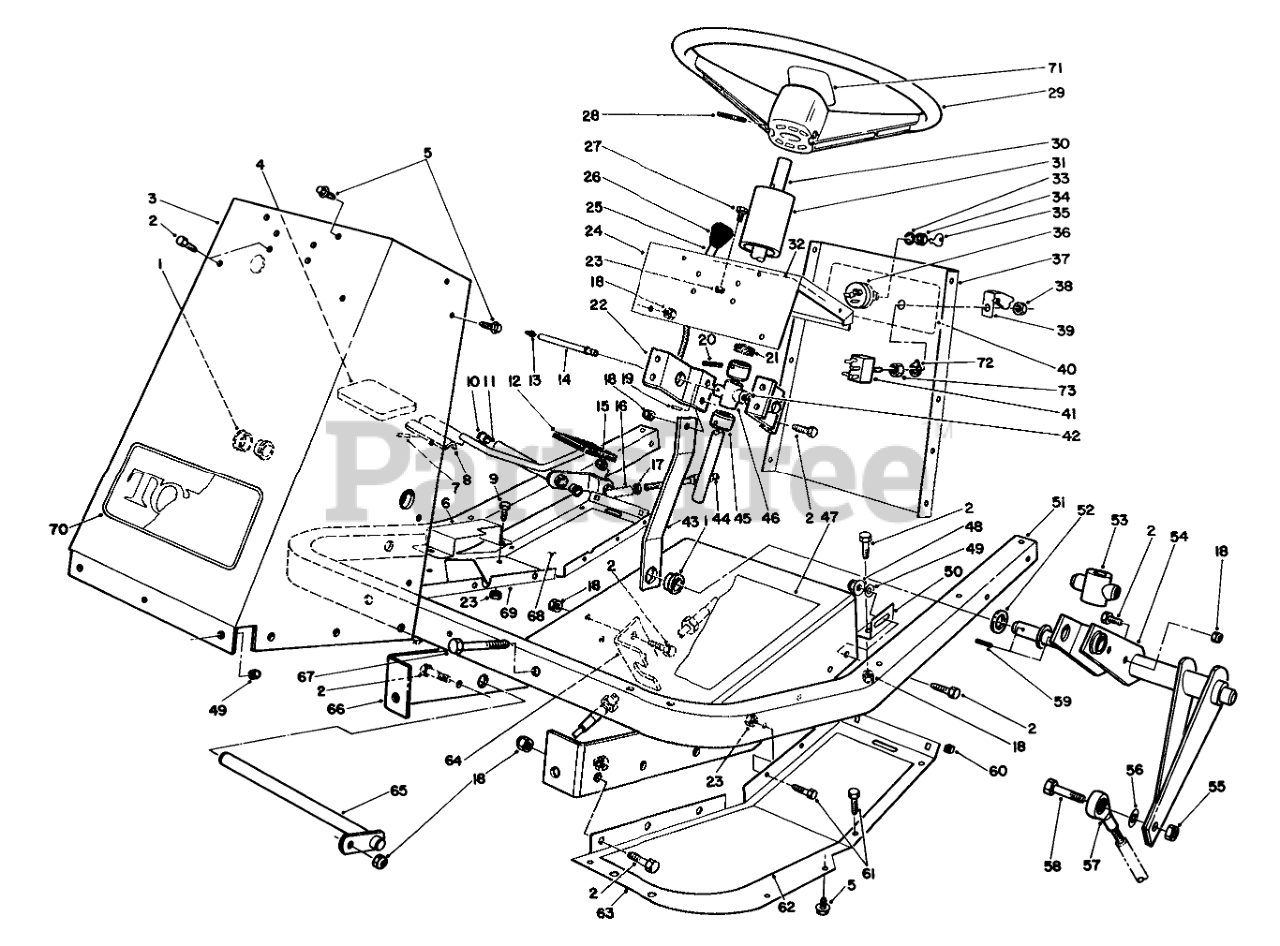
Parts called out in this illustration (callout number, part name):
1	BEARING-FLANGE
2	SCREW-HH
3	Tower-Front
4	FORWARD PEDAL PAD
5	SCREW-HHFTF
6	Footrest-Pedal
7	PIN-SPRING
8	ACCELERATOR PEDAL
9	SCREW-HH
10	BUSHING-FLANGE
11	Pedal-Traction (Incl. Ref. #10)
12	REVERSE PAD
13	FITTING-GREASE
14	TUBE ZERK
15	NUT-LOCK
16	JOINT-BALL
17	NUT-JAM
18	NUT-LOCK, NI
19	3/32 X 9/16 ROLL PIN
20	PIN-SPRING
21	COVER-DUST
22	BRG SUPT BRKT
23	NUT-LOCK, NI
24	Tower-Top
25	CONTROL-CHOKE,THROTTLE
27	SCREW-HH
28	PIN-ROLL
29	WHEEL-STEERING
30	STEERING SHAFT
31	STRG. SHAFT COVER
32	THROTTLE DECAL
33	Washer-Lock
35	KEY-IGNITION
36	Switch-Ignition (Incl. Ref. #33-35)
37	Panel-Tower Rear
39	Cover-P.T.O. Switch (Incl. Ref. # 38, 72 & 73)
40	SWITCH DECAL
41	SWITCH-TOGGLE DPDT
42	WASHER-BELLEVILLE
43	Link-Steering
44	TRACT CONT.CABLE
45	STRG SHAFT COLLAR
46	BRG STEERING SHAFT
47	TUNNEL DECAL
48	NUT-HF
49	WASHER-PLAIN
50	TUNNEL BRKT
51	Frame-Footrest
52	WASHER-THRUST
53	STEER.SHAFT FOLLOWER
54	Follower Lever
55	NUT-HEX
56	WASHER-FLAT
57	BALL JOINT LH
58	SCREW-HH
59	PIN-ROLL
60	NUT-RETAINED
61	SCREW-HH
62	FOOT REST PAD LH
63	Footrest-L.H.
64	TRACT CABLE BRKT
65	PEDAL.SHAFT WA
66	Tunnel
67	SCREW-HH
68	FOOT REST PAD RH
69	Footrest-R.H.
70	DECAL
71	STRG-WHL INSERT TORO
72	Washer
73	NUT-HEX, SPECIAL
